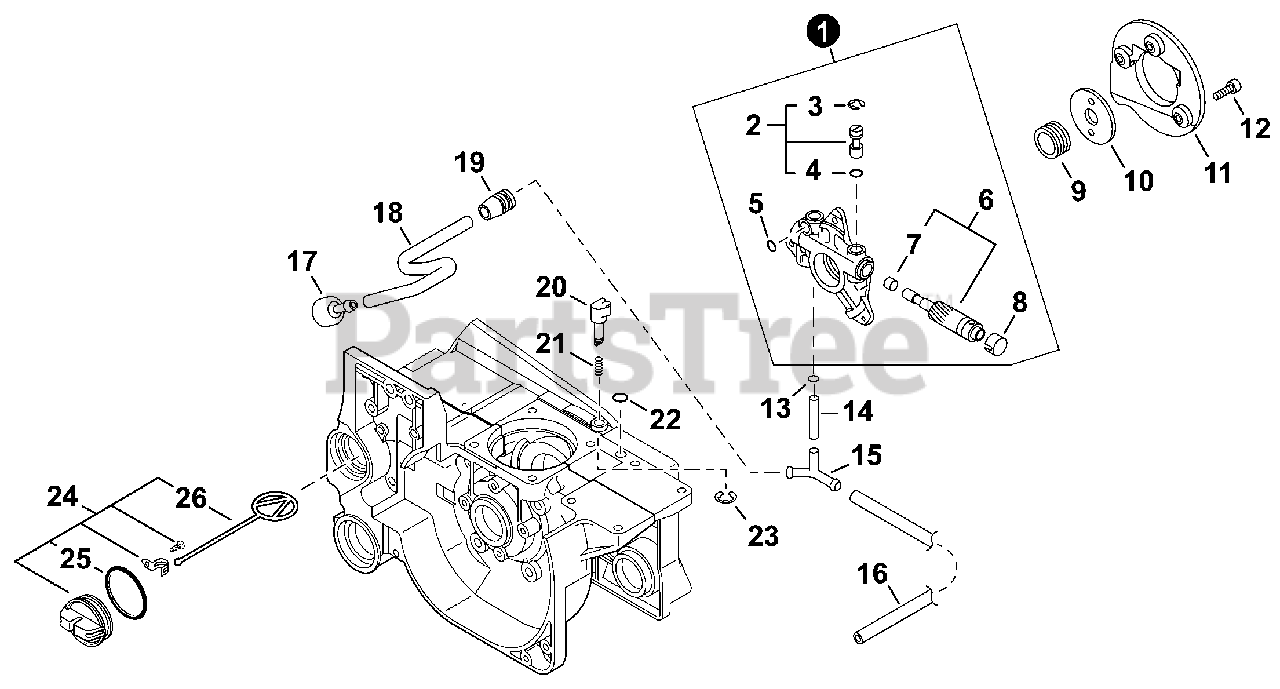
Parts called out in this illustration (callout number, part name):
1	AUTO-OILER ASSY
2	PIN ASSY, CONTROL
5	O-RING 3
6	PLUNGER KIT
8	CAP, PLUNGER
9	GEAR, WORM
11	COVER, OIL PUMP - GRAY
11	COVER, OIL PUMP - ORANGE
12	BOLT 4x14
13	CLIP 6.5 MM
14	PIPE, OIL 3x6x20
15	CONNECTOR, PIPE
16	PIPE, FUEL 3x6x210 BLACK
17	FILTER, OIL
18	PIPE, OIL
20	ADJUSTER, AUTO-OILER - GRAY
20	ADJUSTER, AUTO-OILER - ORANGE
22	O-RING 3
23	E-RING 3
24	CAP ASSY, OIL - GRAY
25	O-RING 25
26	CONNECTOR, CAP L= 60 MM
